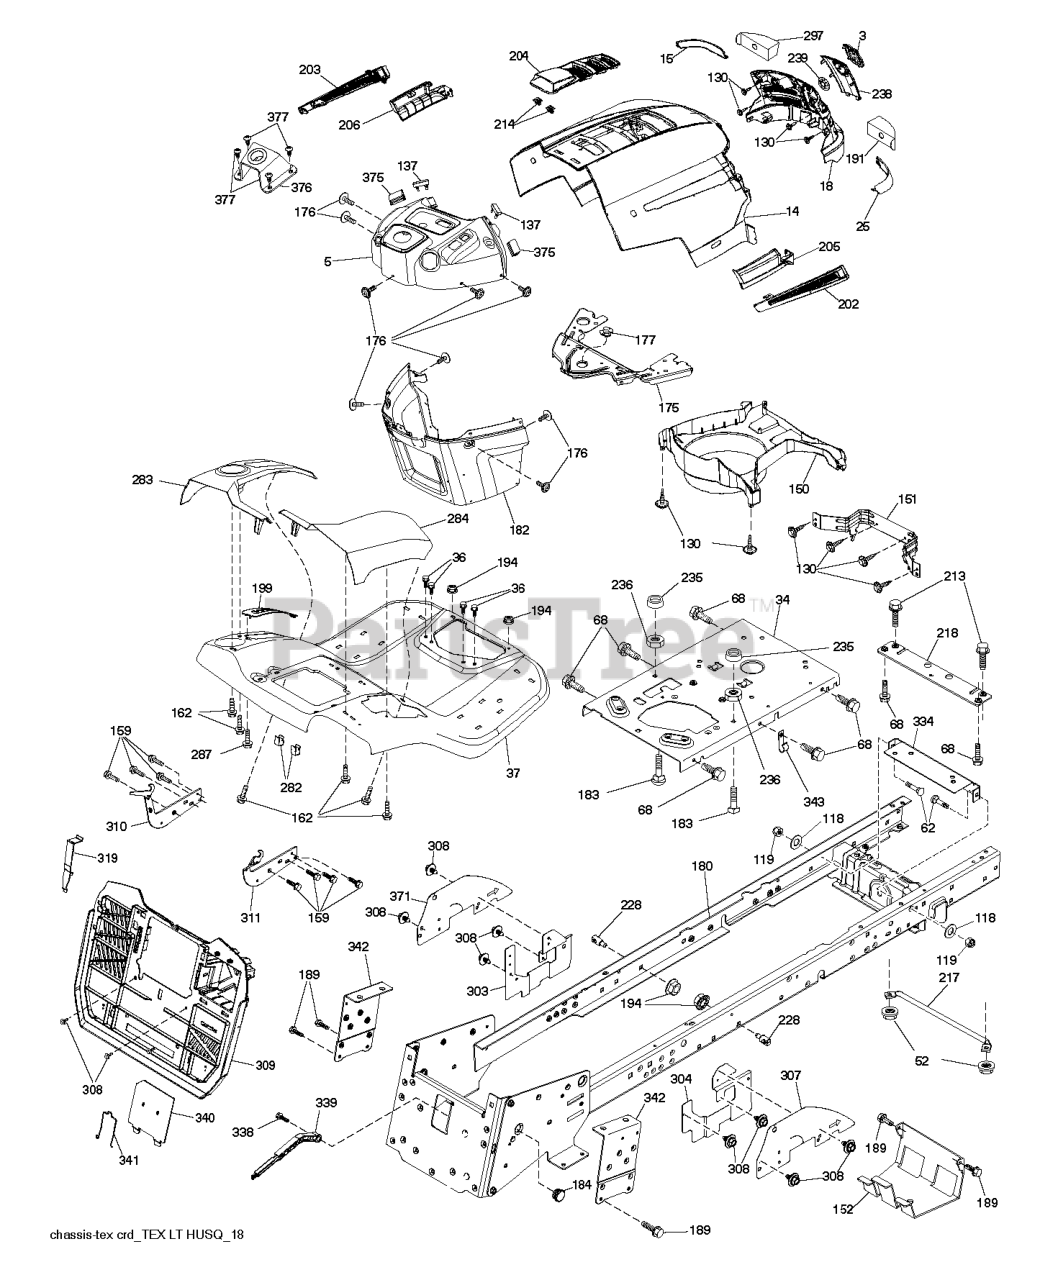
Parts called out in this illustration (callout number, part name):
3	LOGO.HUSQ.GT.LT.CROWN.H
5	DASH.UPPER.HUSQ.LT.MAN.NO-CHK
14	HOOD.HUSQVARNA.LT.ORANGE
15	LENS.HUSQVARNA LT.RH
18	GRILLE.SVC.HUSQVARNA.GREY
25	LENS.HUSQVARNA LT.RH
34	PLATE.ENGINE.10GA.CRD.GENII
36	SCREW 5/16"
37	FENDER.TEX.SRD.CRD.FRN.GUARDS
52	LOCKNUT
62	BOLT D
68	SCR 5/16-18 X 1/2 SELFTAP ZN
118	WASHER
130	SCREW.#10 X 0.750.BOS
137	BUMPER DASH
151	BRACKET PIVOT
152	SHIELD.BROWNING.W/TEX
159	SCREW, 3/8-16X3/4
162	SCREW.HI-LO.CONSOLE
175	CROSSMEMBER
176	SCREW.#10-24X5/8.RN.QU
177	BUSHING STEERING
180	CHASSIS WLDT TEX CRD
182	DASH.LOWER.PREDATOR LT
183	BOLT.5/16-18X1-1/4 FULL THD
189	SCREW
191	INSERT.REFLECTIVE.RH.
194	NUT LOCK HEX FLANGE 5/16-18
199	PLATE DECK LIFT
202	VENT.SIDE.HUSQVARNA.LT.RT
203	VENT.SIDE.HUSQVARNA.LT.LFT
204	SUBASM.TOP.VENT.HUSQ.LT
205	SKIRT.SIDE.HUSQVARNA.LT.RT
206	SKIRT.SIDE.HUSQVARNA.LT.LEFT
213	BOLT
214	CLIP.RETAINER.TINNER.
217	ROD.PIVOT.HOOD
218	X-PIECE.HOOD.STOP.NON/
228	STUD.FASTNER.W/ANTI-ROTATE
235	SPACER FENDER
236	NUT.CENTERLOCK.5/16-
238	TRIM.HUSQ LT.668
282	CLIP.RETAINER.CONSOLE.LT.HUSQ
283	CONSL.DECKLIFT.LH.SRD.TEX.CRD
284	CONSL.SHIFT.GEAR.RH.SRD.GREY
287	SCREW 1/4X20
297	INSERT REFLECTIVE
303	SHIELD.LWR.LH.LT.30"CRDSRD.PNT
304	SHIELD ISO RH LOWER CRD GEN 1
307	SHIELD UPPER,RH,FENDERSHIFT,CR
308	BOLT.5/16-18UNCX3/4 W/SEMS.BLK
309	BACKPLATE.TEX.CRD.GEN.1
310	LH.ADJUST.HANGER.BRACKET.ASM
311	RH.ADJUST.HANGER.BRACKET.ASM
319	BRACKET.ACTUATOR.BAGGER.SRD
334	BRACKET.ENGINE
338	BOLT BOLT SHOULDER
339	LEVER LEVER BAGGER
340	DOOR.PNT.BATTERY.TRY.TEX.CRD.
341	LATCH.BATTERY.DOOR.TCRD
342	SUPPORT.PNT.FENDER.CRD.TEX
343	CLIP CLIP
371	SHIELD.UPPER.CRD.SRD.ISO
375	BUMPER CLIP-ON. DASH 1"
376	MOUNT.ASM.HUSLT.UPPER.STRNG
377	SCREW 10 X 1/2 ZN PL PHIL PAN
